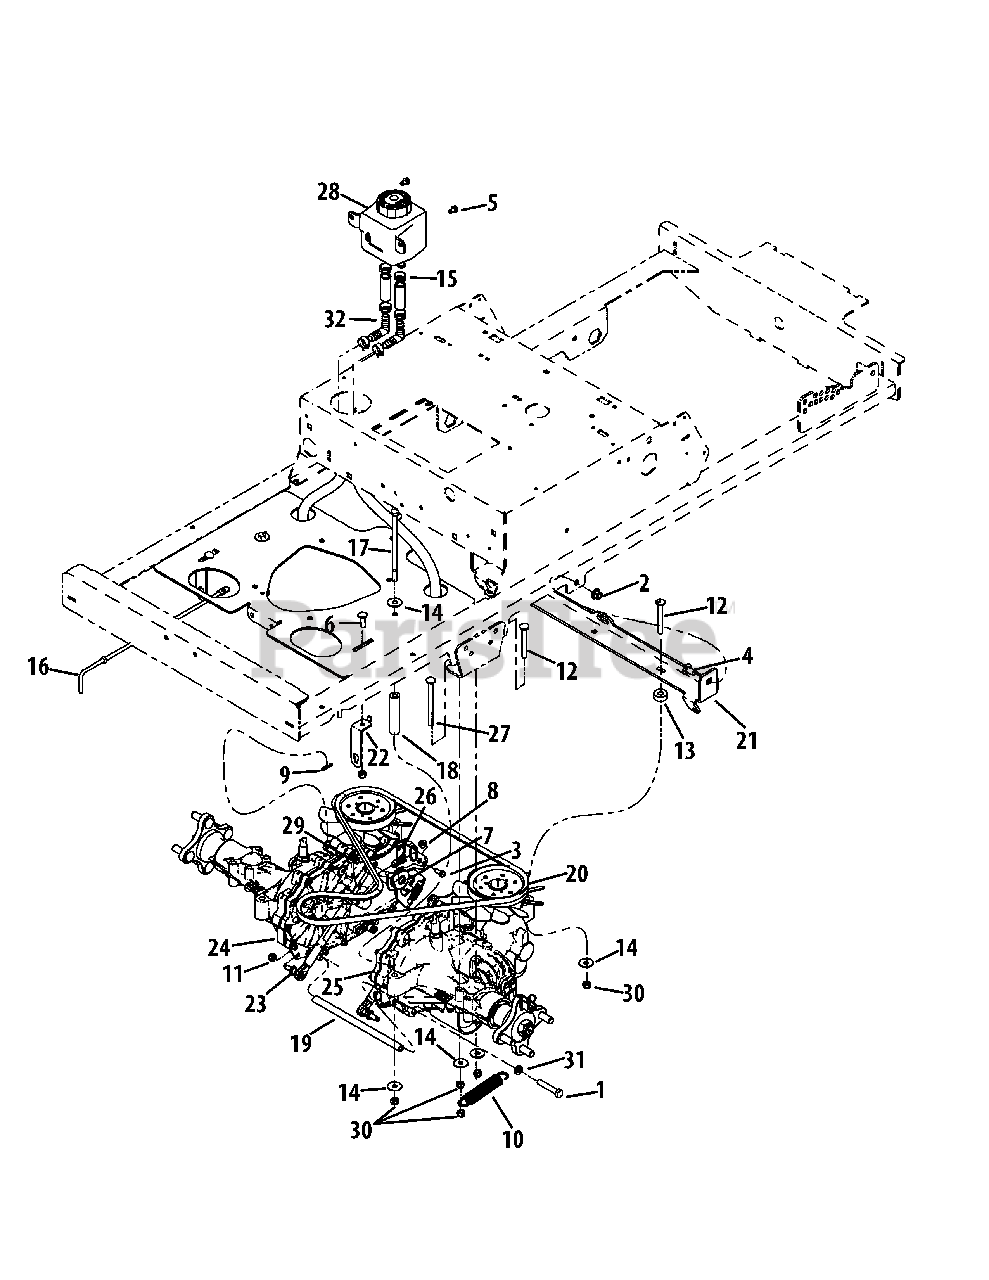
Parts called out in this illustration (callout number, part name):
1	Hex Screw, 3/8-16 x 2.00
2	Flange Counterlock Nut, 3/8-16
3	Hex Screw, 1/4-20 x .620
4	Carriage Bolt, 3/8-16 x .75
5	Hex Flange Screw, 1/4-20 x .500
6	Carriage Bolt, 5/16-18 x 1.00
7	Shoulder Bolt, 1/4-28 x .38 x .465
8	Flange Toplock Nut, 1/4-20
9	Hair Pin, 1/8 x 1.125 x .072
10	Extension Spring, .865 x 4.7 x .12
11	Nylock Nut, M8-1.25
12	Carriage Bolt, 5/16-18 x 2.75
13	Spacer, .406 x 1.00 x .38
14	Washer, .313 x 1.06 x .062
15	Hose Clamp, .750
16	Pump Relay Rod
17	Hex Screw, 5/16-18 x 6.00
18	Spacer, .375 x .750 x 3.30
19	Transmission Support Tube
20	V-Belt
21	Transmission Bracket
22	Neutral Bracket
23	Damper
24	LH Transmission
25	RH Transmission
26	Control Arm Damper Bracket
27	Carriage Bolt, 5/16-18 x 4.0
28	Expansion Tank Assembly
29	Jam Nut, 1/4-28
30	Hex Lock Nut, 5/16-18
31	Lock Washer, 3/8
32	Elbow, 90
